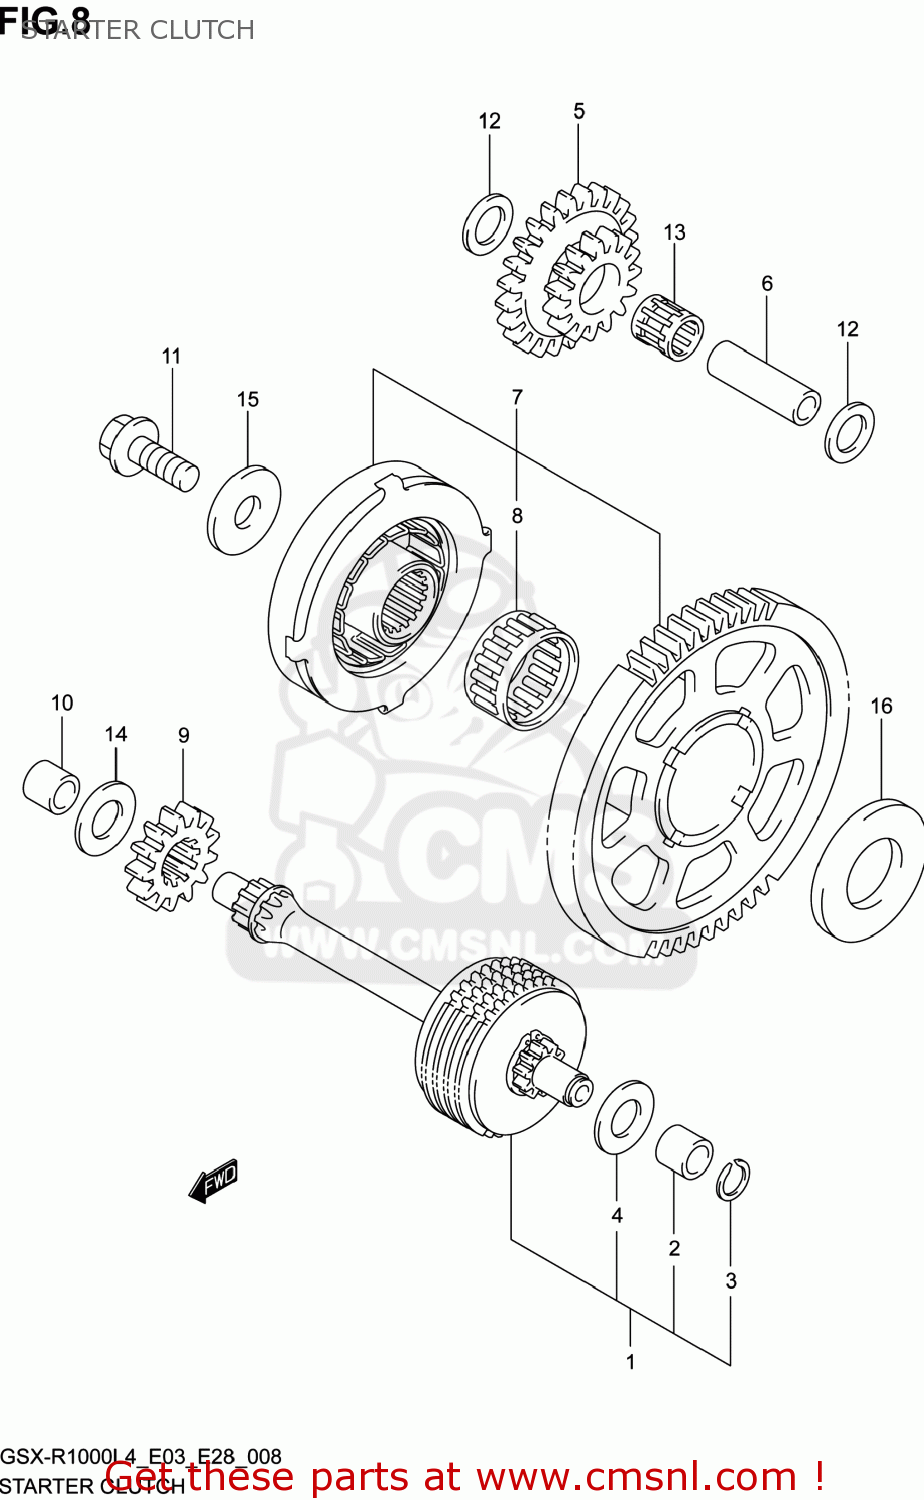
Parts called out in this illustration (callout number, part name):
1	LIMITER ASSY,START ID GR NO.1
2	BUSH,LIMITER GEAR SHAFT
3	CIRCLIP
4	WASHER
5	GEAR,STARTER IDLE NO.2
6	PIN,PISTON
7	CLUTCH SET,STARTER
8	BEARING(26X31X16)
9	GEAR,LIMITER DRIVEN
10	BUSH,LIMITER GEAR SHAFT
11	BOLT(10X23)
12	SHIM(12X20X1)
13	BEARING(12X16X16)
14	WASHER
15	WASHER
16	WASHER
